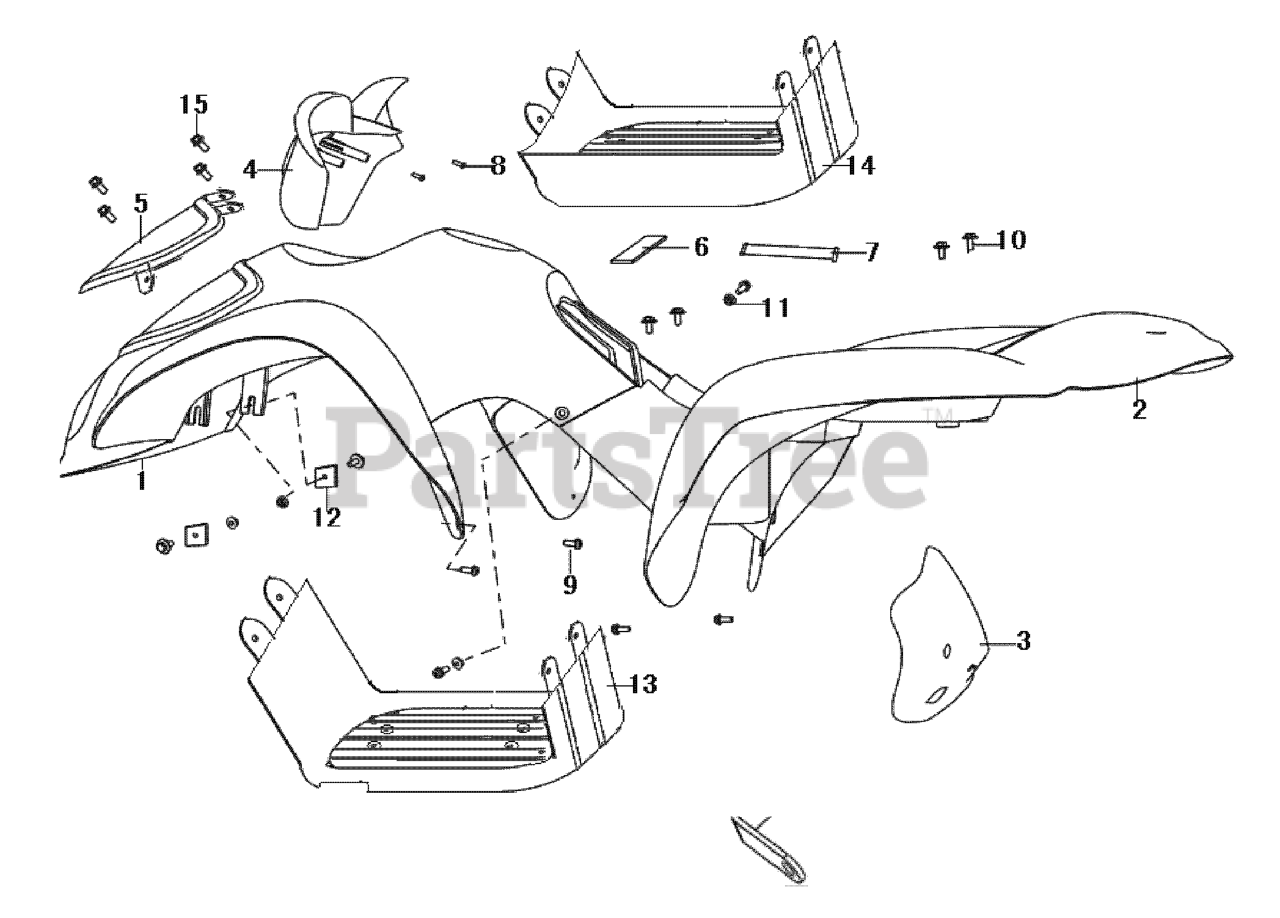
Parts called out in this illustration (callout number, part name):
1	COWLING, FRONT (RED)
2	COWLING, REAR (RED)
3	COVER, REAR (RED
4	COWLING, HANDLEBAR (RED)
5	COVER, FRONT (RED)
6	BAND, BATTERY
7	BAND, TOOL KIT
10	SCREW W/WASHER
13	FOOTREST COVER, LEFT
14	FOOTREST COVER, RIGHT
